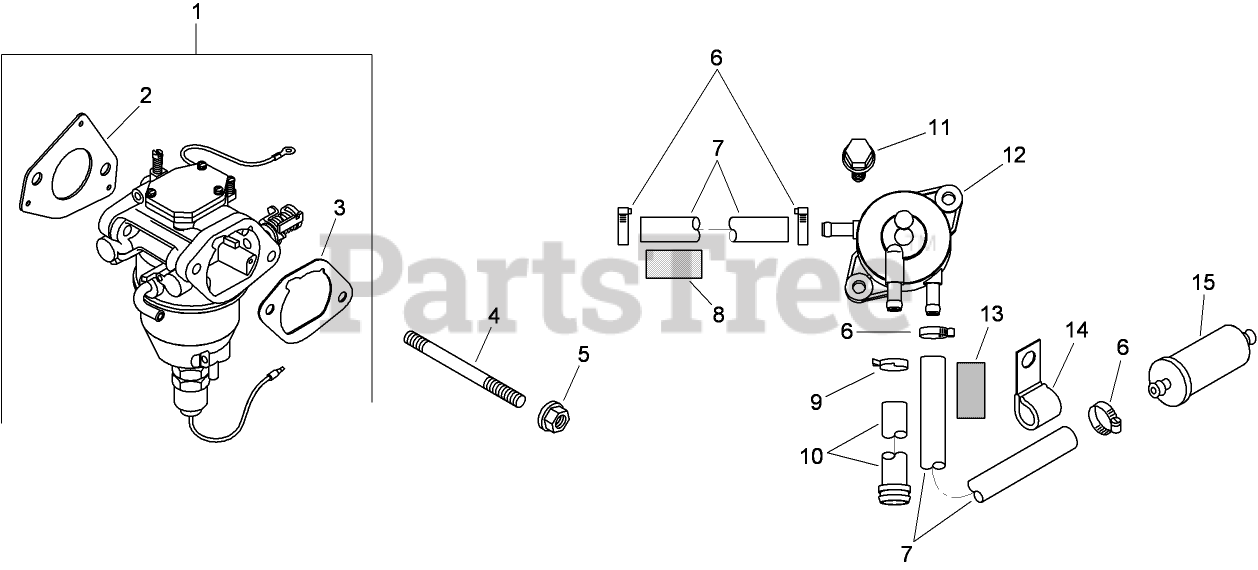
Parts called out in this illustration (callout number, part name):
1	CARBURETOR KIT W/GASKETS (INCLUDES 2-3)
2	GASKET-CARBURETOR
3	GASKET-BASE, AIR CLEANER
4	STUD (M6X1.0X106)
5	NUT-FLANGE (M6X1.0)
6	CLAMP-HOSE, SPRING (1/2)
7	LINE-FUEL (24-CUT TO LENGTH)
8	SLEEVE-ABRASION, ANTI
9	CLAMP-HOSE
10	HOSE-FUEL PUMP W/CLAMP (INCLUDES 10)
11	SCREW-TAP (M6X1.7X18)
12	PUMP-FUEL
13	SLEEVE-ABRASION, ANTI
14	Filter-Fuel
15	CLIP-CABLE
